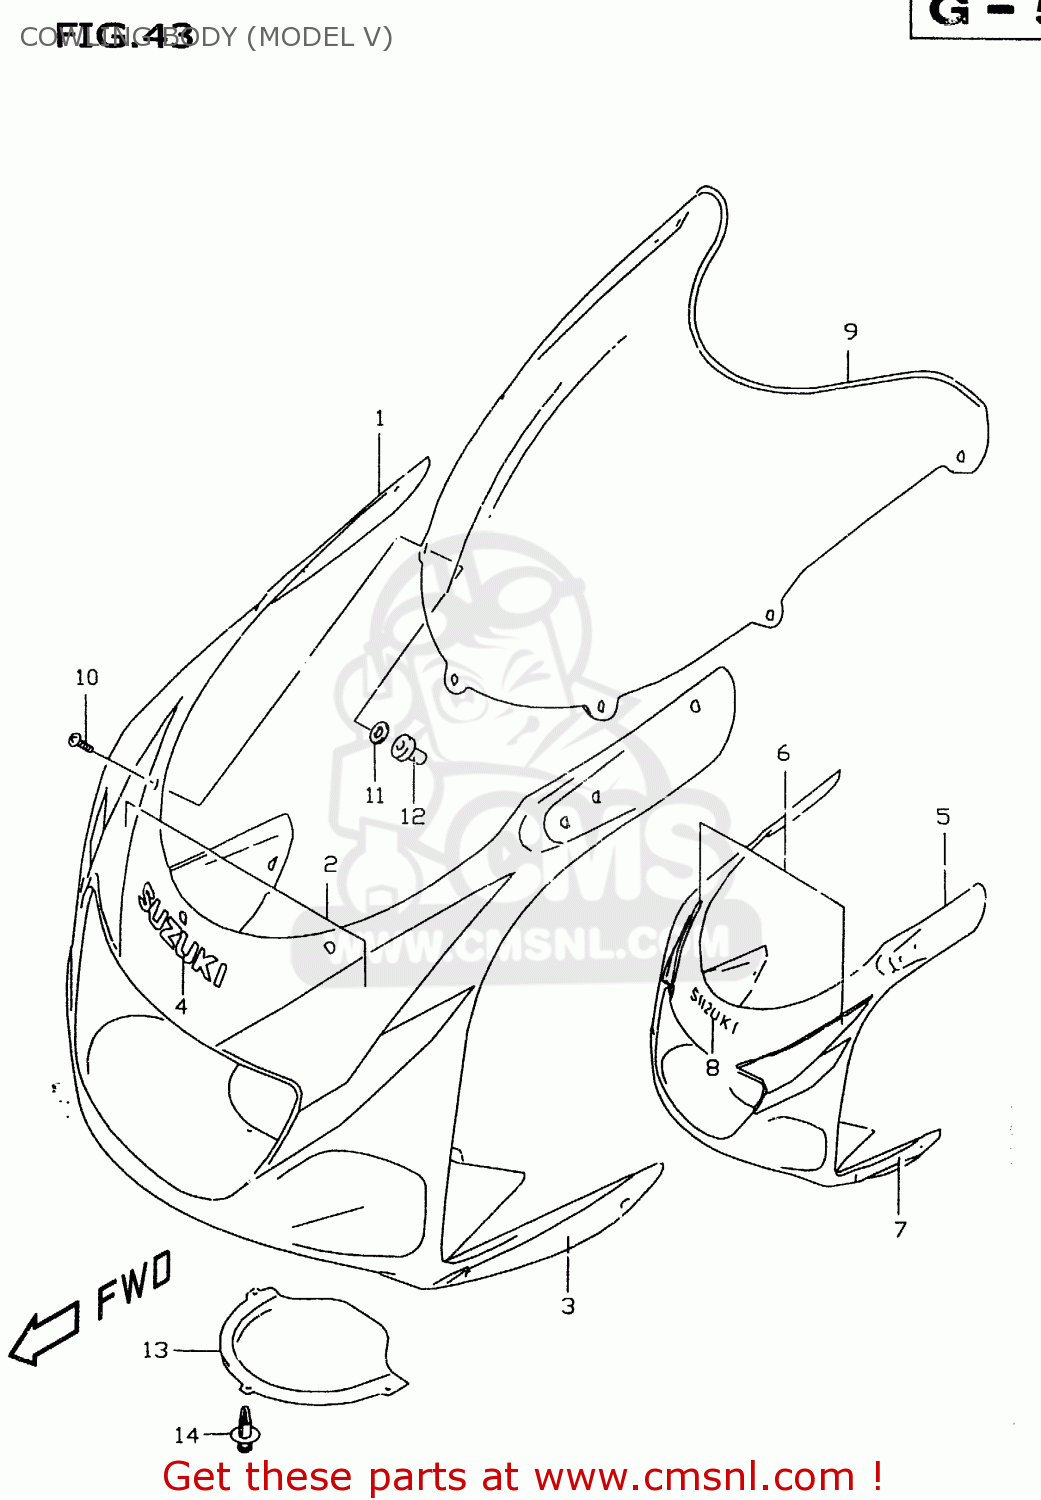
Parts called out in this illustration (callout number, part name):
1	COWLING ASSY,BODY
2	TAPE SET,COWL BODY FR
3	TAPE SET, SIDE (BLACK)
4	EMBLEM,FR
5	COWLING ASSY,BODY
6	TAPE SET,COWL BODY FR
7	TAPE SET,COWL BODY SIDE
8	EMBLEM,SUZUKI
9	WINDSCREEN
10	SCREW(5X14)
11	WASHER
12	NUT
13	LID,BODY COWLING,LOWER
14	CLIP(BLACK)
